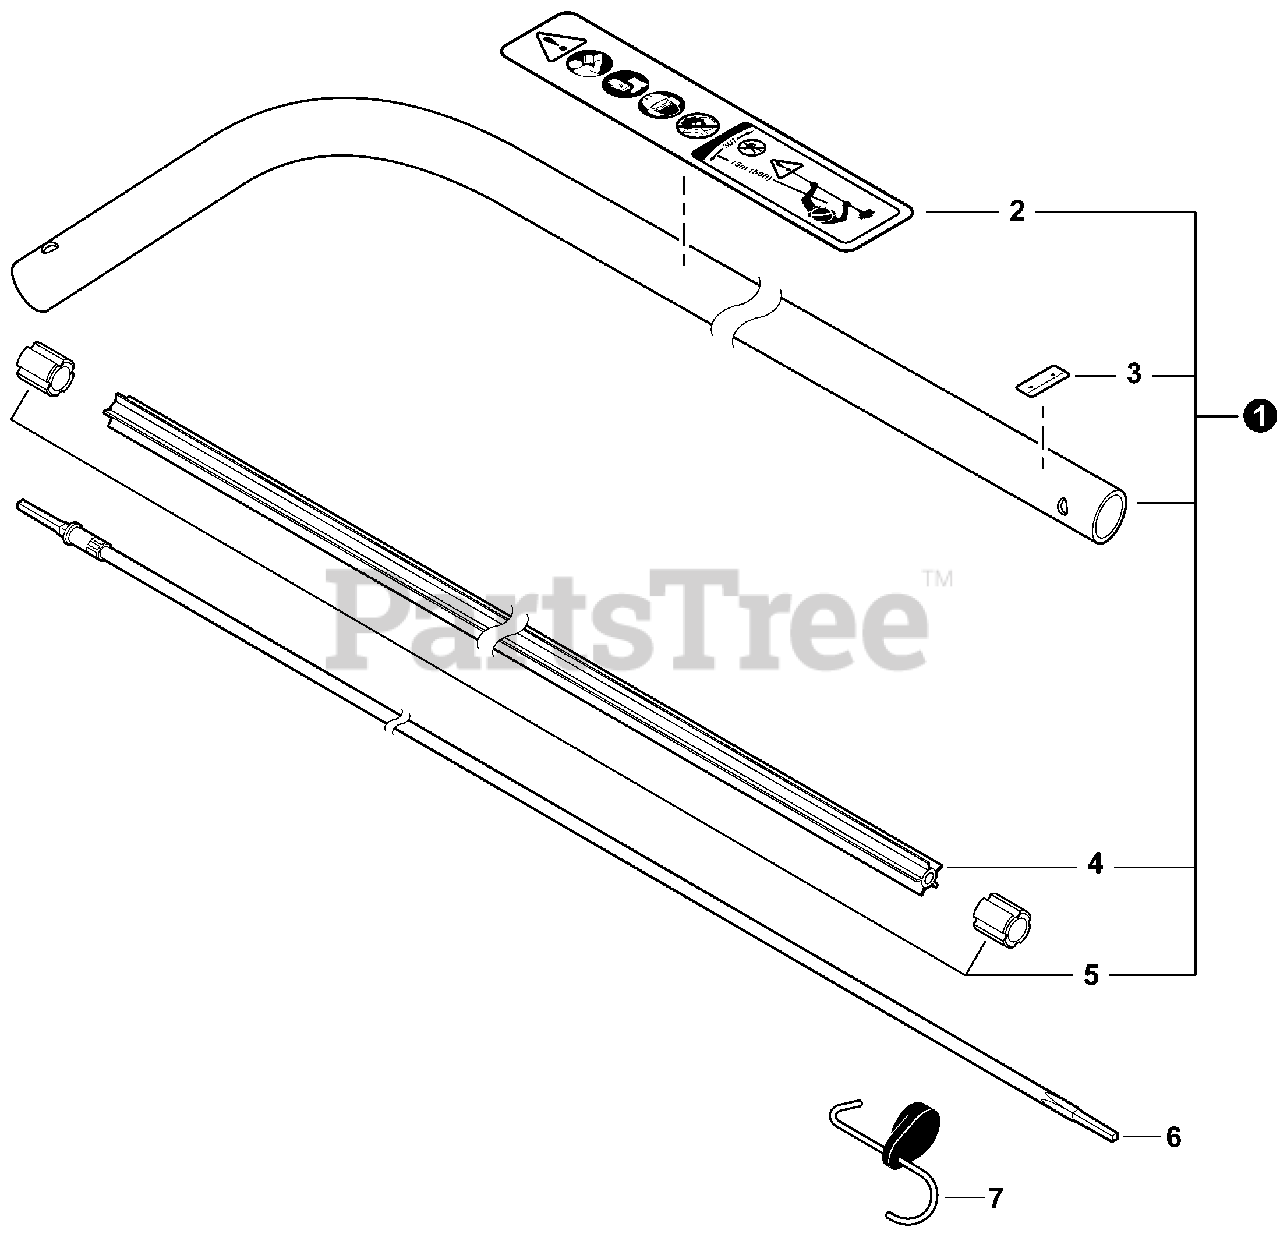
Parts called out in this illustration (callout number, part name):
1	MAIN PIPE ASSY
2	LABEL, CAUTION
3	LABEL - ALIGNMENT
4	LINER - FLEXIBLE
6	DRIVESHAFT - FLEXIBLE
7	HANGER, ATTACHMENT
